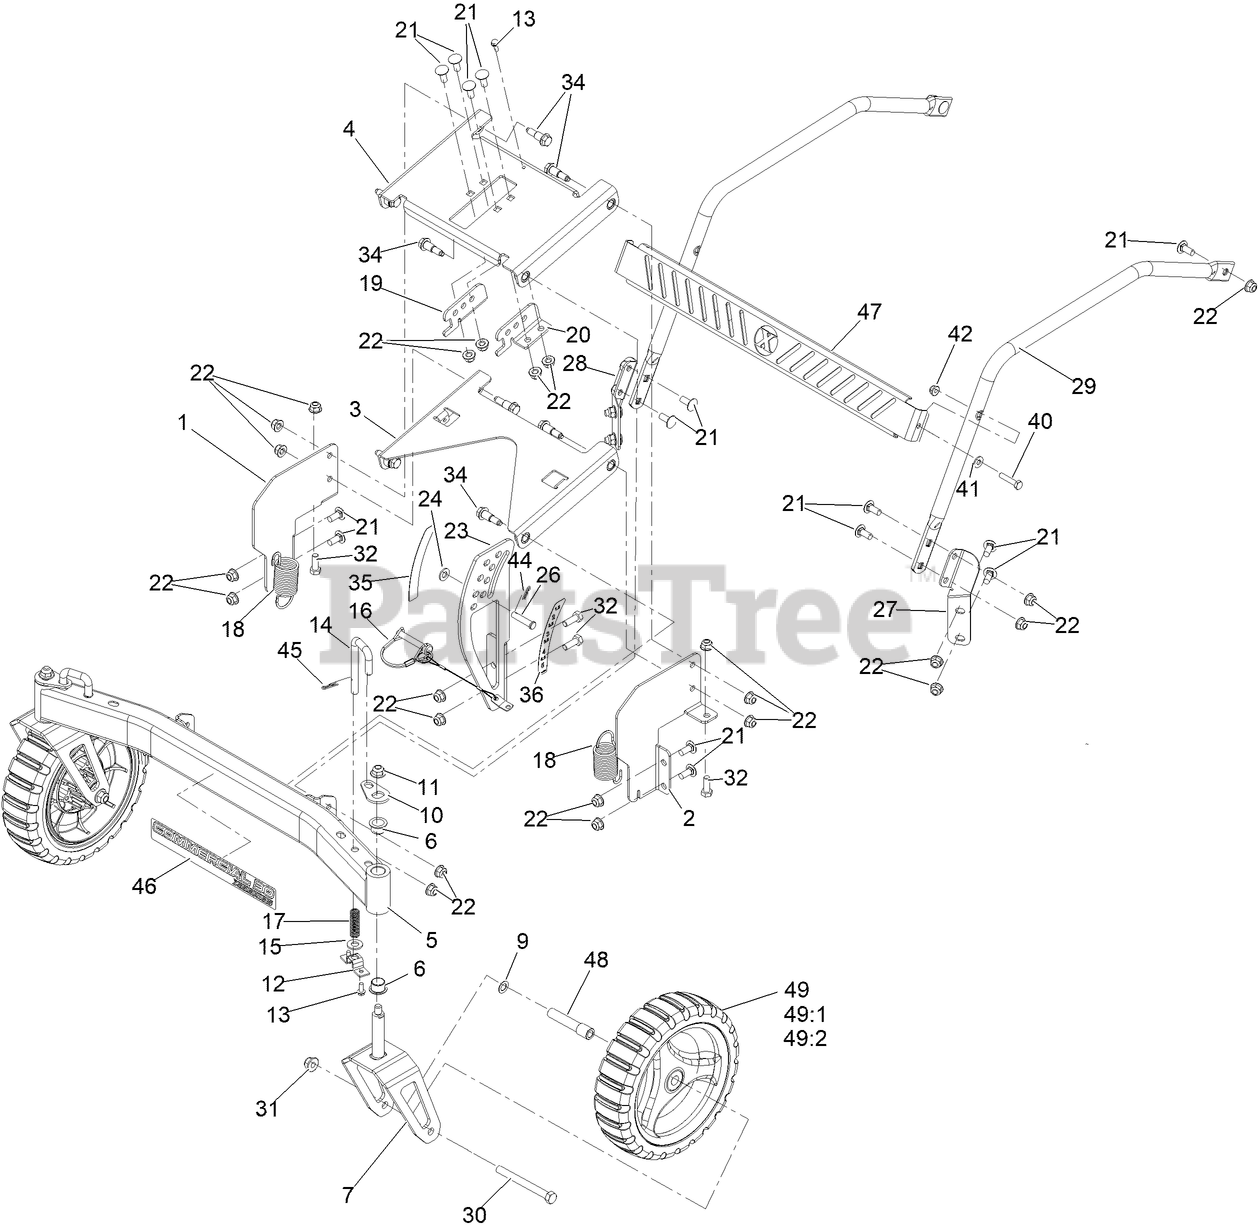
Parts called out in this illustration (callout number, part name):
1	Caster Deck Bracket
2	Caster Deck Bracket
3	Link Plate ASM [red]
4	Link Plate ASM [red]
5	Front Axle
6	Bushing
7	Caster Fork
9	Washer-Flat
10	Locking Plate
11	Nut-HF, NI
12	Caster Pin Bracket
13	SCREW-TAPTITE
14	Caster Lock Pin
15	WASHER-FLAT
16	Locking Pin W/Lanyard
17	Spring-Compression, Pin
18	Spring-Extension, HOC Assist
19	HOC Position Plate RH
20	HOC Position Plate LH
21	SCREW-CARR
22	NUT-HF, NI
23	HOC Plate
24	WASHER-PLAIN
26	PIN-CLEVIS
27	Brace Bracket LH
28	Brace Bracket RH
30	SCREW-HH
31	NUT-HF, NI
32	SCREW-HH
34	Bolt-Shoulder, Flange
35	Decal-HOC
36	Decal-HOC
40	SCREW-HH
41	WASHER-FLAT
44	Pin-Hair
45	Pin-Hair
46	DECAL-COMM 30 X-SERIES
48	Spacer-Wheel
49	WHEEL ASM, 9" W/BEARINGS
49:1	WHEEL ASM, 9
49:2	BEARING-BALL
